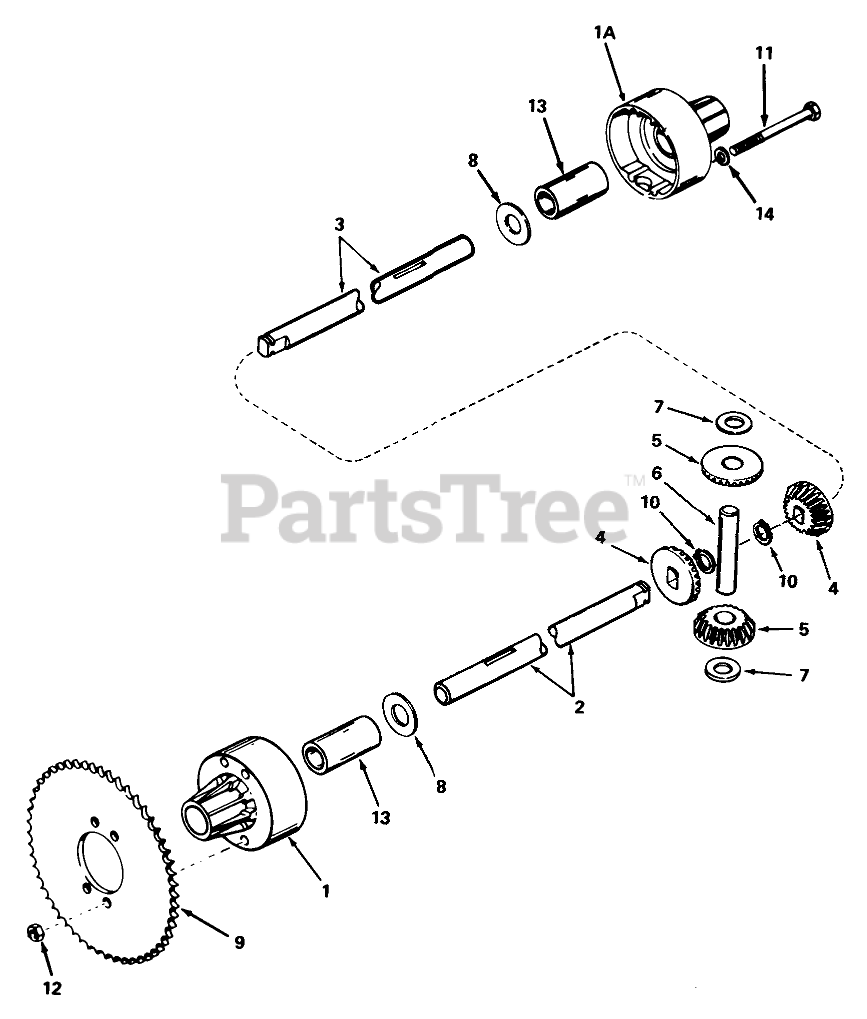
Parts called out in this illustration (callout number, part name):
1	Housing-Differential Carrier (Incl. #13)
1A	Housing-Differential Carrier (Incl. #13)
2	Axle (9-1/8" Long)
3	Axle (18-5/8" Long)
4	Bevel Gear
5	Gear Pinion
6	Pin Drive
7	Washer Thrust
8	Washer
10	Ring-Snap
11	Screw-Hex Hd.
12	Nut-Lock
13	Bushing
14	Washer
